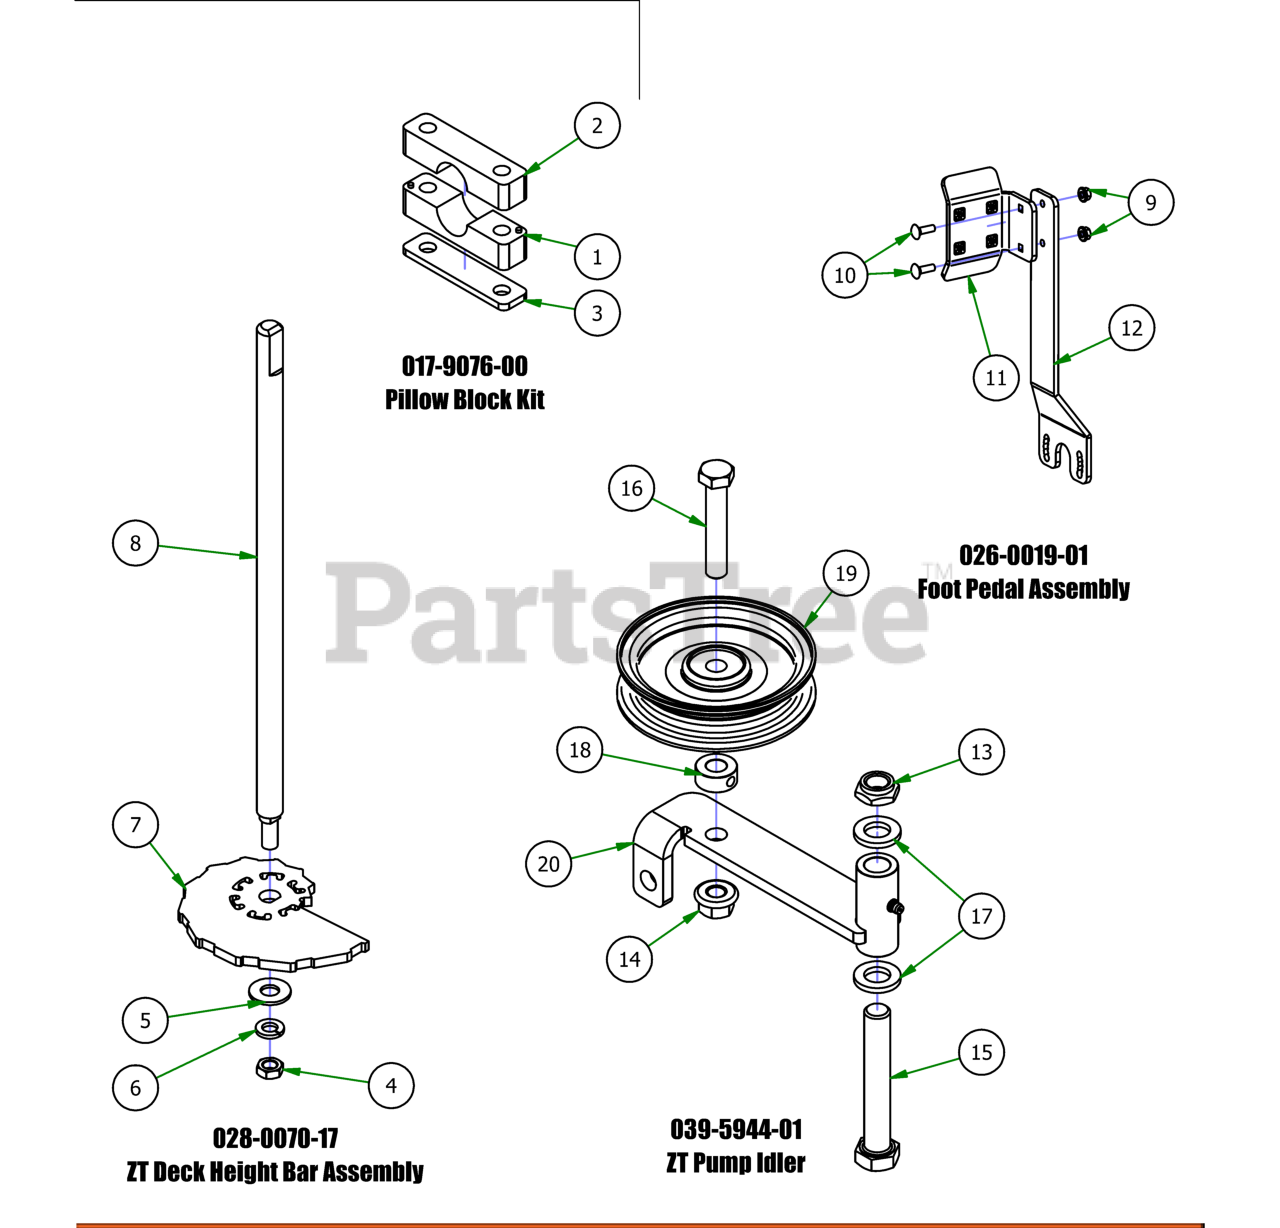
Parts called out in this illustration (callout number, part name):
1	Pillow Block MZ male
2	Pillow Block MZ female
3	Pillow Block Strap
4	3/8-24 HEX NUT ZINC YELLOW
5	3/8 FLAT WASHER USS (1" OD) ZINC
6	3/8 SPLIT LOCKWASHER ZINC
7	2017 MZ/ZT Cam Plate
8	2017 Deck Height Dial Rod ZT
9	5/16-18 NYLON INSERT FLANGE LOCKNUT ZINC
10	5/16-18 X 1 CARRIAGE BOLT (GR.8) ZINC
11	2017 MZ/ZT Shallow Foot Pedal
12	2017 MZ/ZT Deck Pedal Lever
13	5/8-11 NYLON INSERT JAM LOCKNUT ZINC
14	1/2-13 NYLON INSERT FLANGE LOCKNUT ZINC
15	5/8-11 X 4 HEX CAP SCREW (GR.8) ZINC YELLOW
16	1/2-13 X 2-3/4 HEX CAP SCREW (GR.5) ZINC
17	.635 ID X 1.120 OD X .140 THICK FLAT WASHER NYLON
18	1/2 SOLID SHAFT COLLAR (W/1 SET SCREW) ZINC
19	4 3/4" Idler Pulley
20	Pump Idler Bracket
